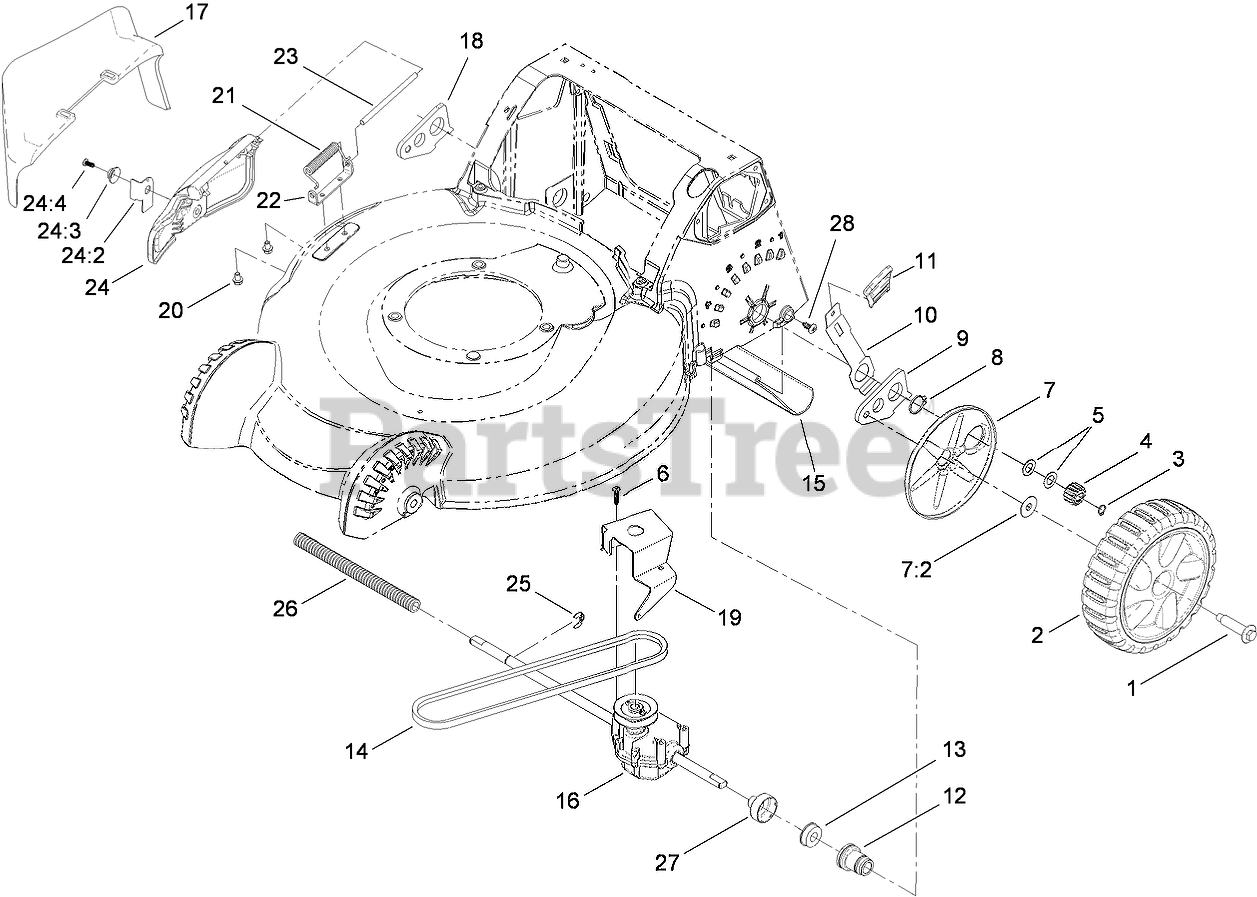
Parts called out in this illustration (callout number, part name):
1	BOLT-SHOULDER
2	REAR WHEEL ASM
3	RING-RETAINING
4	GEAR-PINION, 15T
5	WASHER-PLAIN
6	SCREW-PLASTITE
7	WHEEL COVER ASM
7:2	WASHER-STEPPED
8	RING-RETAINING
9	ARM-REAR PIVOT, LH
10	ARM-SPRING, REAR
11	KNOB-HOC
12	RETAINER-BEARING
13	BEARING-BALL
14	V-BELT
15	SHIELD-TRAILING
16	TRANSMISSION ASM
17	CHUTE-DISCHARGE, SIDE
18	ARM-REAR PIVOT, RH
19	BRACKET-TRANSMISSION
20	SCREW-HWH
21	SPRING-TORSION
22	BRACKET-COVER
23	ROD-COVER
24	DISCHARGE DOOR ASM
24:2	LATCH-DOOR
24:3	CAP-DOOR
24:4	SCREW-PLASTITE
25	RING-CLIP, LOCKING
26	CONDUIT-CONVOLUTED, SPLIT
27	CAP-BEARING
28	SCREW-PTH
